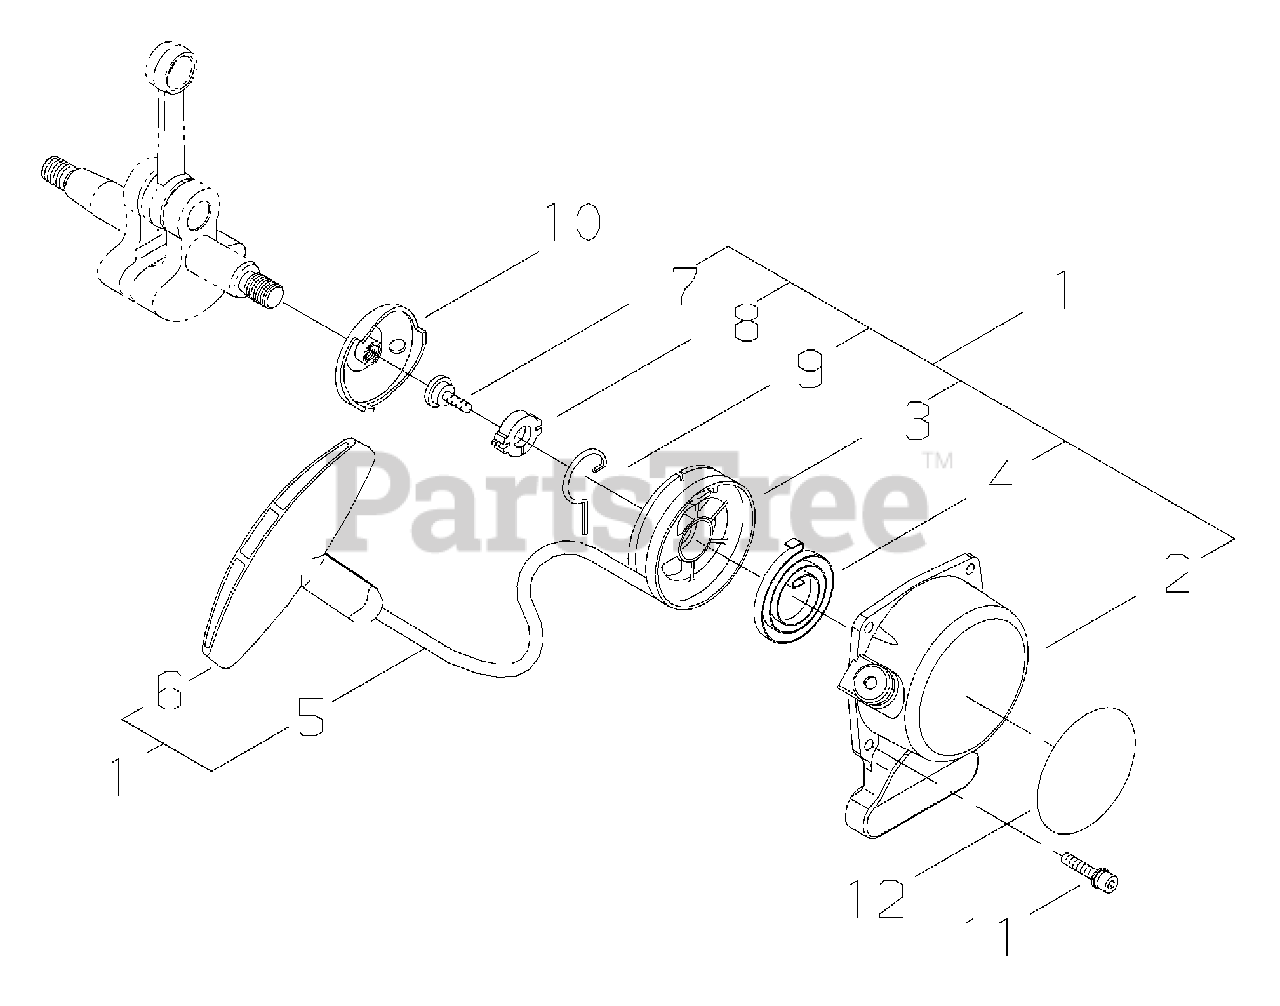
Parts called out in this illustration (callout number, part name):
1	STARTER ASSY
2	CASE, STARTER
3	REEL, ROPE
4	SPRING, REWIND
5	ROPE, STARTER
6	GRIP, STARTER
7	SCREW - 5
8	WASHER - 5
9	PAWL, STARTER
10	STARTER PAWL ASSY
11	SCREW - 4X14
12	LABEL - C4
